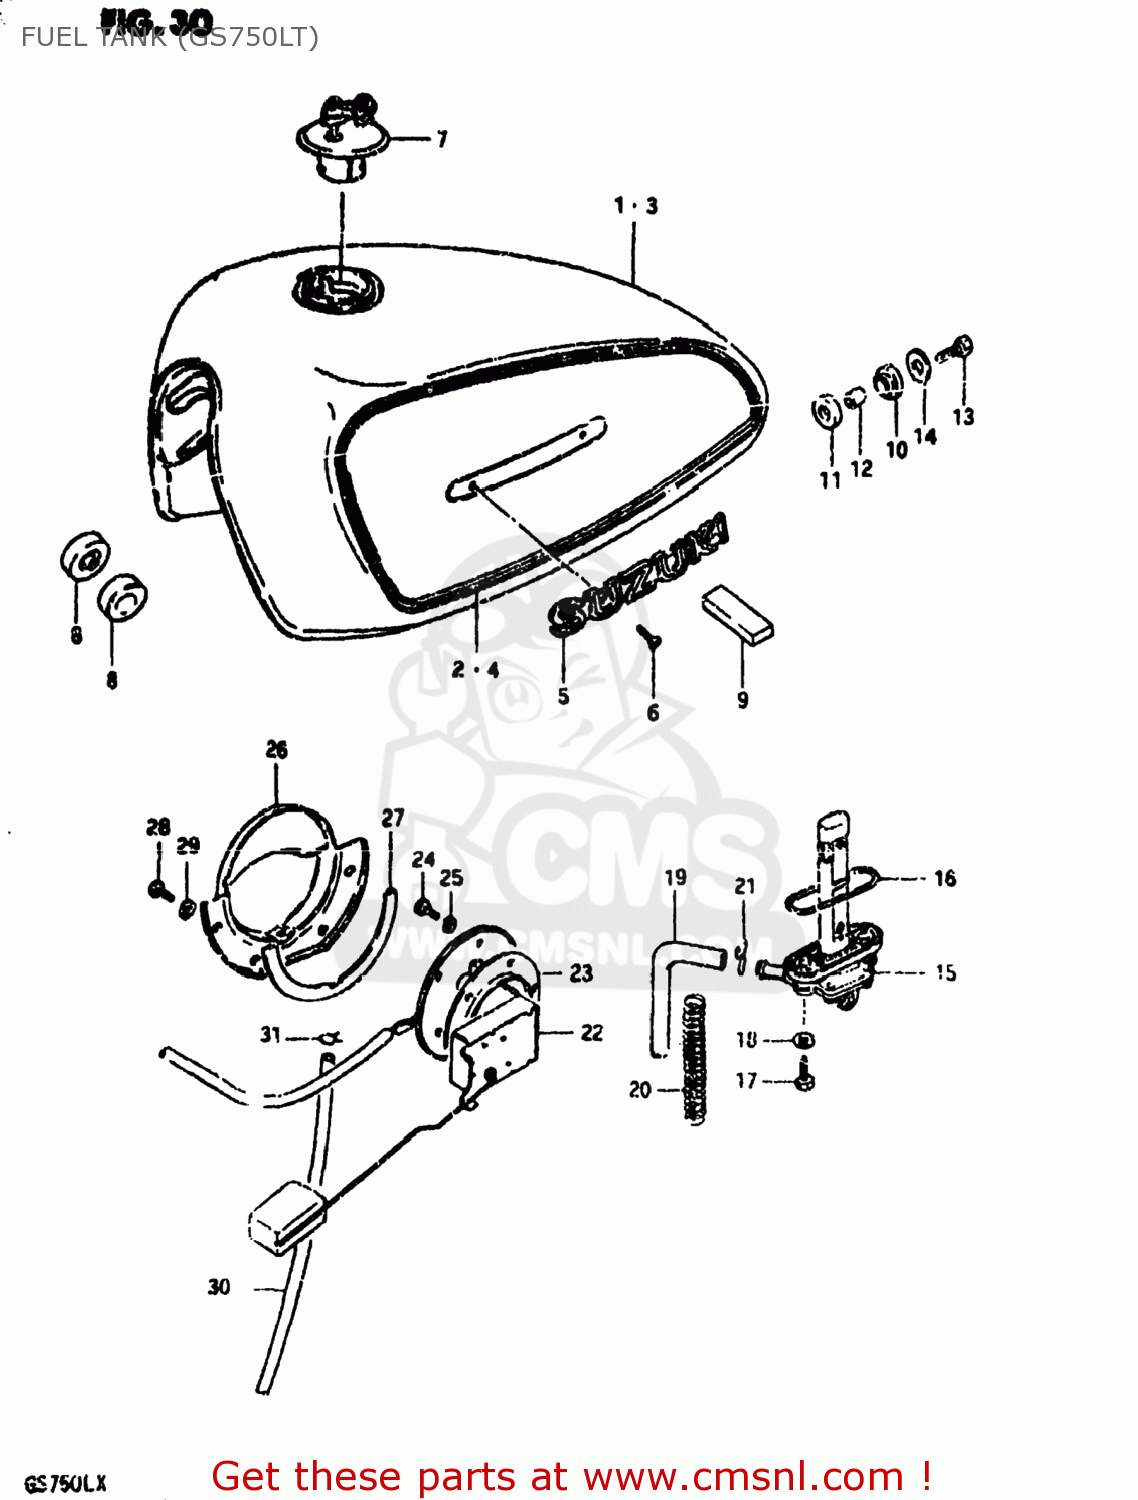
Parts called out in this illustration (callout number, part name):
1	TANK ASSEMBLY,FUEL
2	TAPE SET,FUEL TANK
3	TANK ASSEMBLY,FUEL
4	TAPE SET,FUEL TANK
5	EMBLEM
6	SCREW 3X6
7	CAP SET,FUEL TANK
8	CUSHION
9	CUSHION
10	CUSHION
11	CUSHION
12	SPACER(8.5X12X19)
13	BOLT
14	WASHER (8.5X29X1.6)
15	COCK ASSY,FUEL
16	GASKET (NAS)
17	SCREW (6X25)
18	GASKET
19	HOSE
20	SPRING
21	CLIP
22	GAUGE ASSEMBLY,FUEL LEVEL
23	GASKET,FUEL LEVEL GAUGE (NAS)
24	BOLT
25	LOCK WASHER
26	PLATE,FUEL DRAIN
27	GASKET,FUEL DRAIN PLATE (NAS)
28	SCREW
29	LOCK WASHER
30	HOSE,FUEL
31	CLIP
